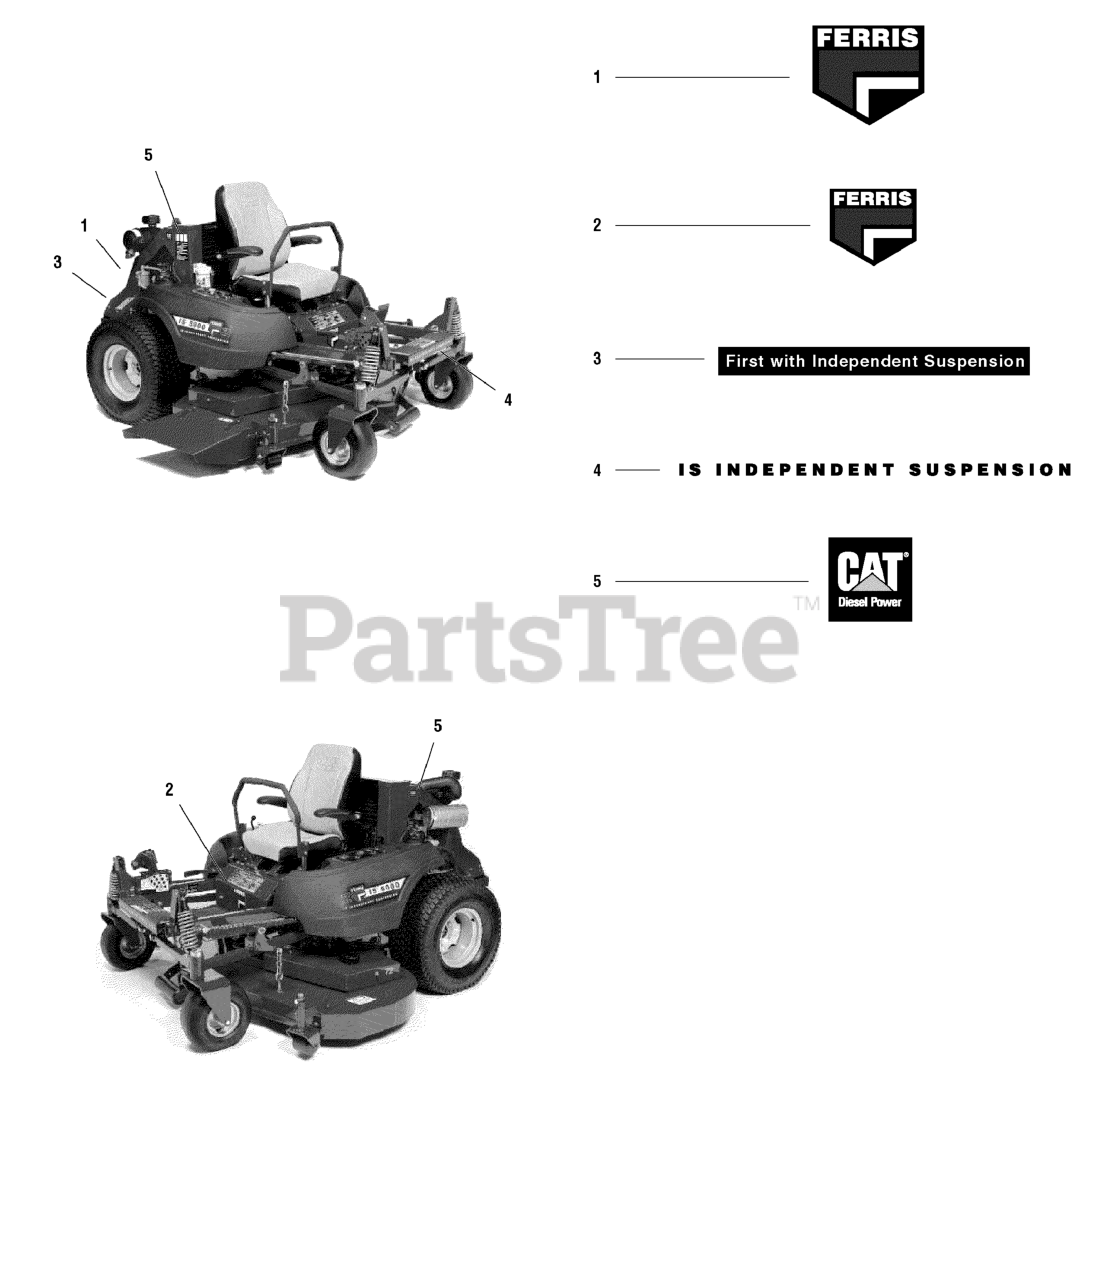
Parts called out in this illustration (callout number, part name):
1	DECAL, Ferris Logo, 6-3/8"
2	DECAL, Ferris Logo, 5"
3	DECAL, First w/ Independent Suspension
4	DECAL, IS Independent Suspension
5	DECAL, CAT Diesel Power
